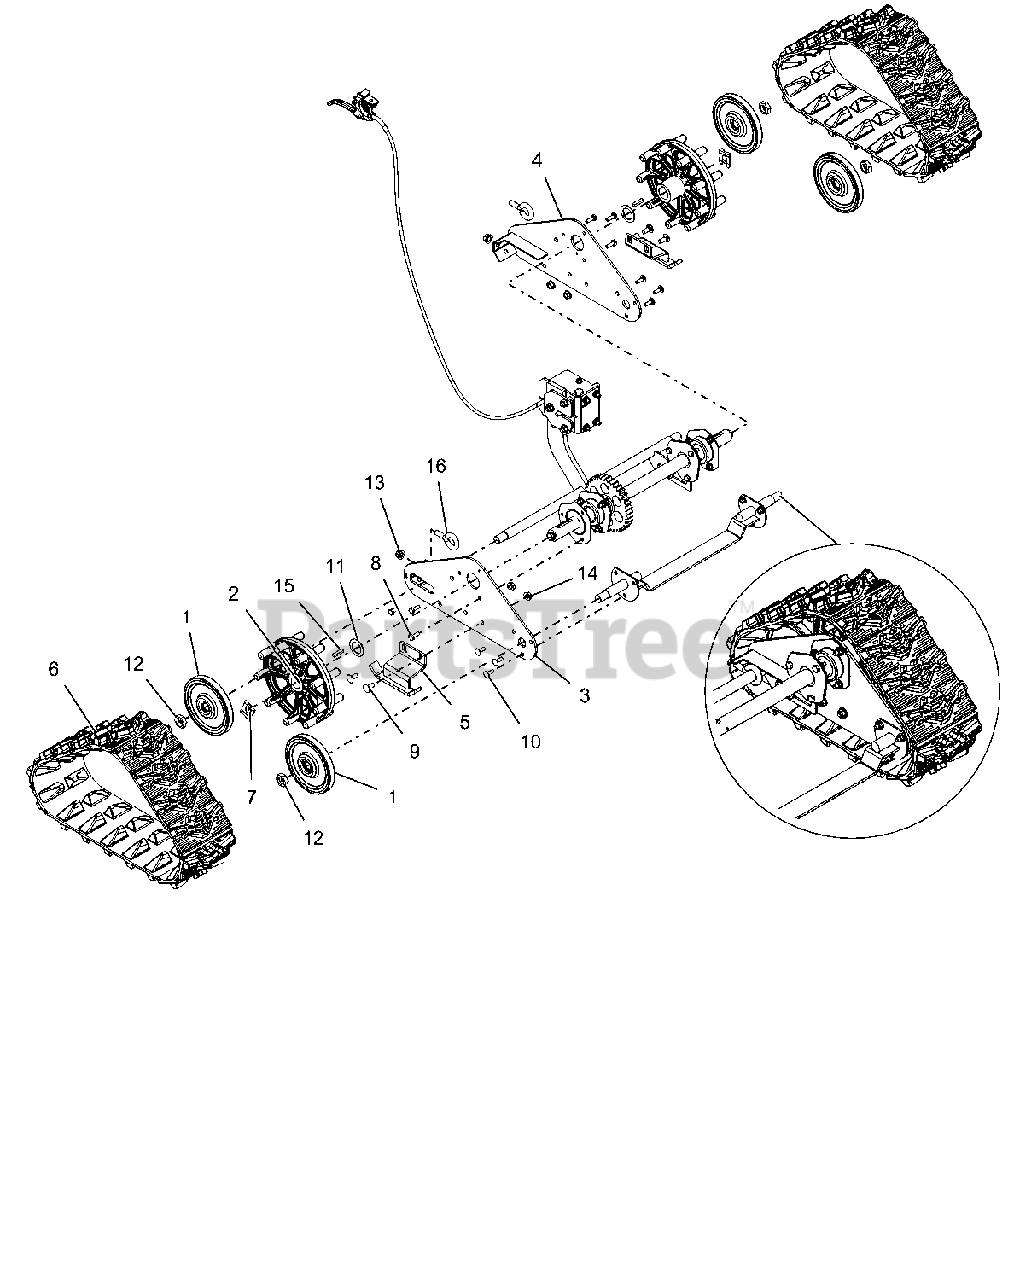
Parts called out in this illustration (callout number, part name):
1	WHEEL, BOGIE - SINGLE BEARING
2	WHEEL, MACHINED DRIVE
3	SIDE PLATE, RH COMPACT BLACK
4	SIDE PLATE, LH-COMPACT TRACK B
5	RUNNER, GUIDE-CMPT TRACK BLACK
6	TRACK, RUBBER COMPACT
7	CLIP, SNAP .625 DIA
8	@BLT-HEX .25-20X.75 GR5 YWZC
9	@BLT-RDHDSQNK .31-18X.75 G5YZ
10	@BLT-RDHDSQNK .25-20X.75 G5YZ
11	WSHR-FL-STL 1.010X1.505X.062YZ
12	@NUT-LK-NYL .625-18 YWZC
13	NUT-LK-CTR-FLG .38-16 YWZC
14	@NUT-LK-TOP-FLG .31-18 YWZC
15	KEY-RECT .25X.188X1.00
16	BLT-EYE .375-16X.880 YWZC
